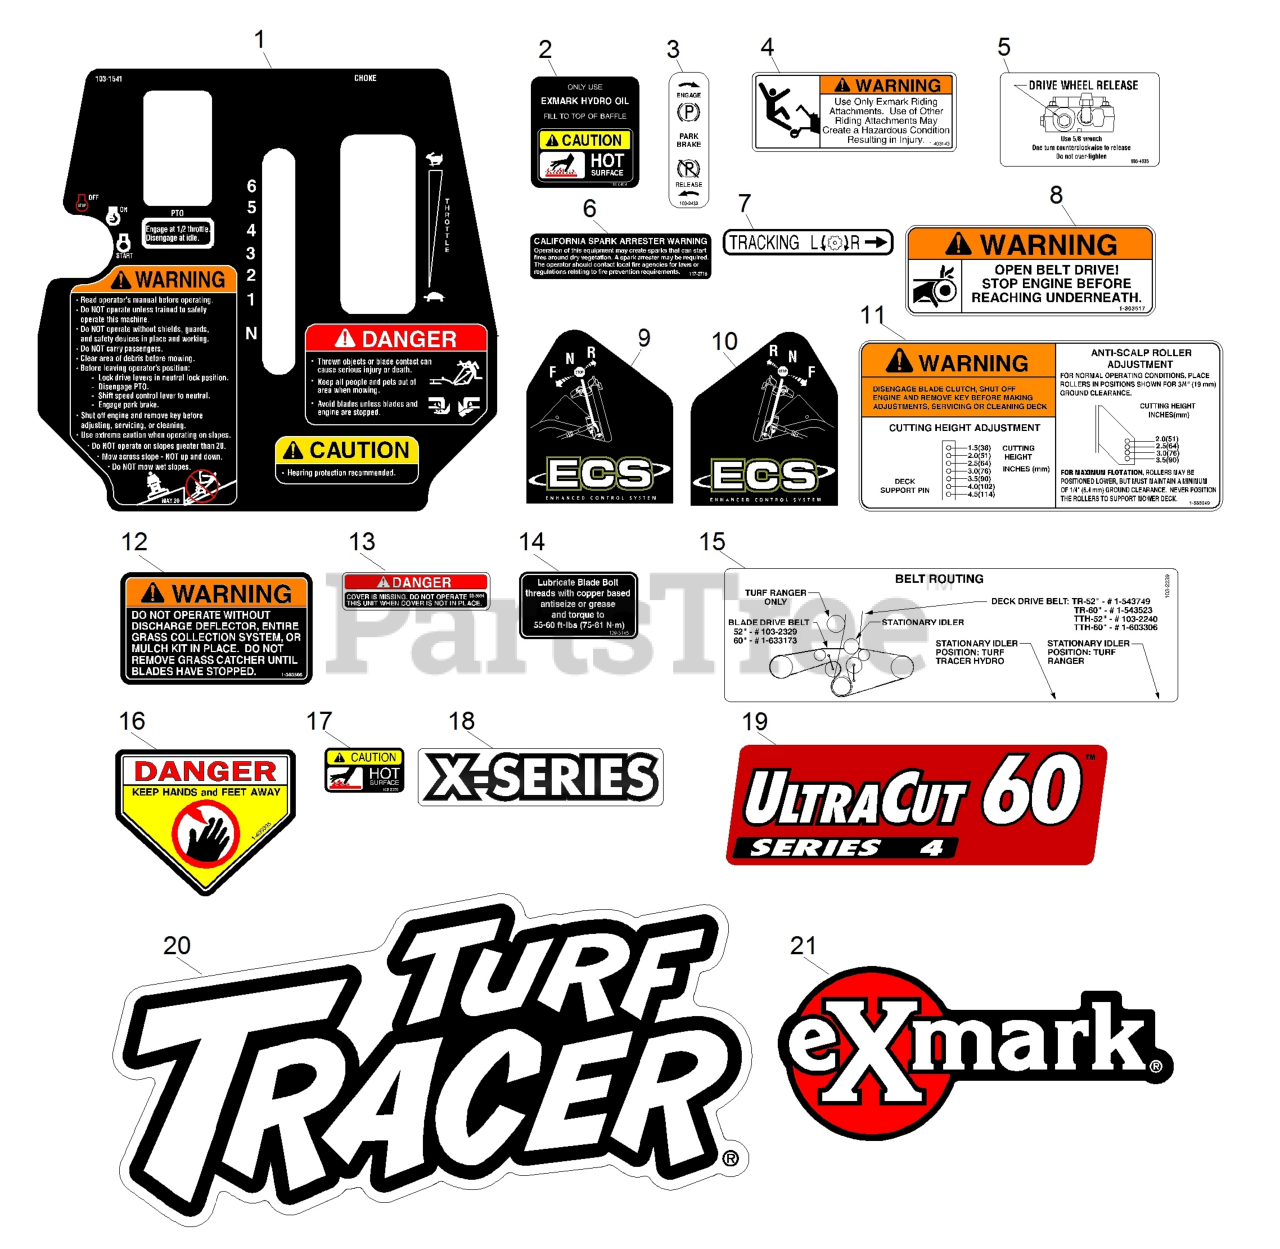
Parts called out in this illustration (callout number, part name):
1	DECAL,TTH ECS CONSOLE
2	DECAL-HYDRAULIC TANK
3	DECAL,PARKING BRAKE
4	DECAL,SULKY WARNING
5	DECAL,DRIVE RELEASE
6	DECAL-ARRESTER, SPARK
7	DECAL,TRACKING ADJUST
8	DECAL,BELT DRIVE
9	DECAL,LH ECS INSTRUCTION
10	DECAL,RH ECS INSTRUCTION
11	DECAL,ANTI SCALP
12	DECAL-WARNING, DISCHARGE
13	DECAL-COVER, MISSING
14	DECAL,BOLT TORQUE
15	DECAL,BELT ROUTING
16	DECAL-DANGER
17	DECAL-CAUTION
18	DECAL-X-SERIES
19	DECAL,ULTRACUT 60 SERIES
20	DECAL,TTH MODEL
21	DECAL,EXMARK LOGO
